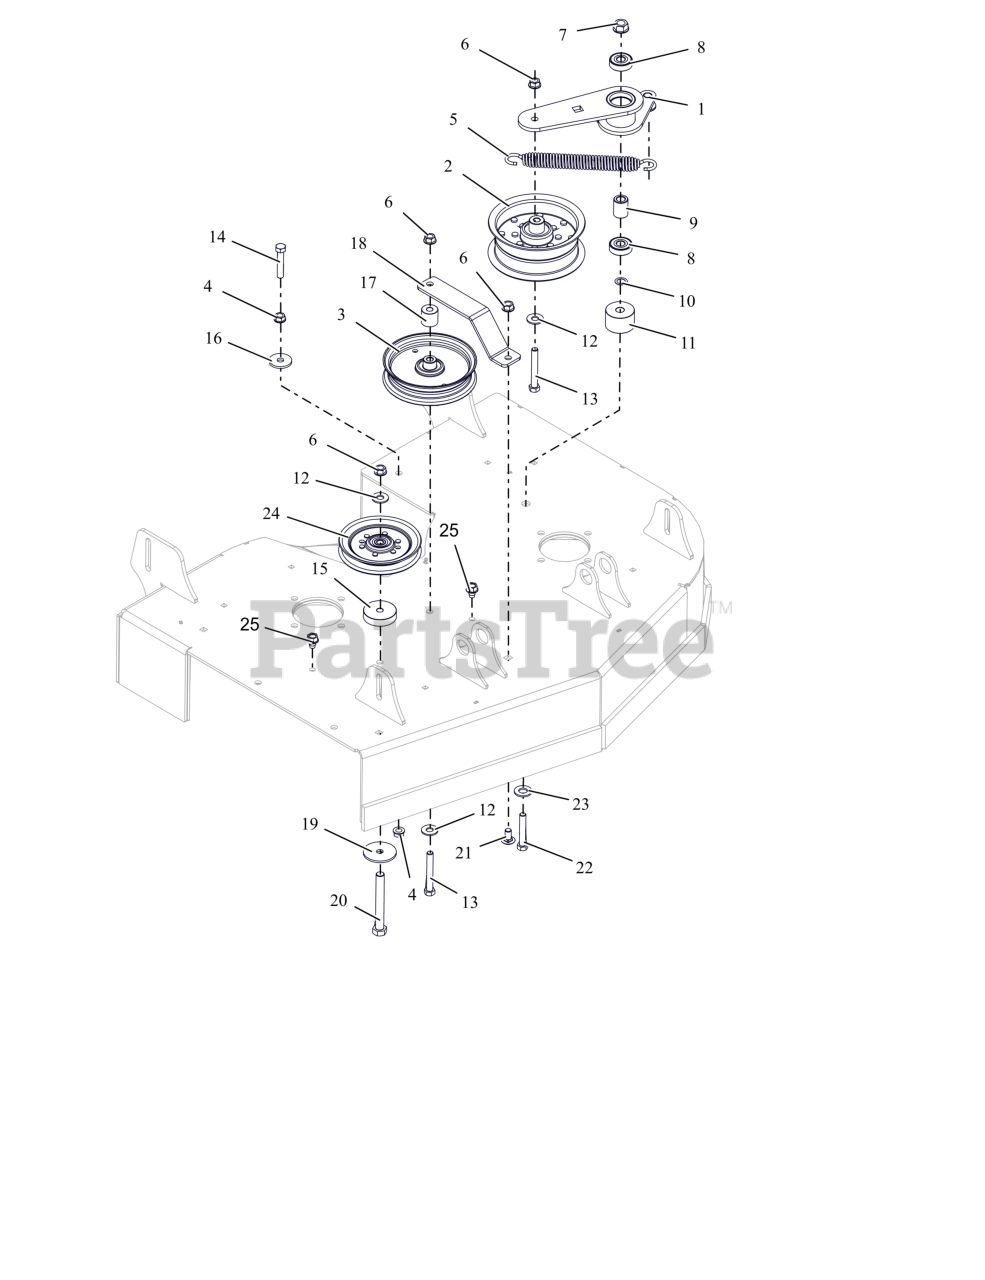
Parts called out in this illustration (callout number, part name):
1	WLDMT- IDLER ARM- 32" DECK
2	PULLEY, FLAT 5.00X2.36X.375
3	IDLER- FLAT - 5.00" X .75"
4	NUT, SPNLK-FLG .38-16 G5 ZCC
5	SPRING- EXTENSION
6	NUT-LK-CTR-FLG .375-16 GF ZCC
7	NUT-LK-CTR-FLG .500-13 GG ZCC
8	BRG-BALL .500X1.38X.437
9	SPACER .510 X .867 X 1.1485
10	WASHER, .500X.750X.020 THRUST
11	SPCR- DECK IDLER ARM
12	WSHR,FLT .438X1.00X.083 ZCC
13	BLT, HEX .38-16X2.75 G5 ZCC
14	BLT,HEX .38-16X2.00 G5 ZCC
15	SPCR, .380 X 2.000 X .500
16	WSHR,FLT .406X1.375X.135 ZCC
17	BUSHING- SLV .380 X .750 X .76
18	BRKT- 32" FIXED IDLER MTG(RED)
19	WSHR-FL-STL 0.406X2X0.125 ZCC
20	BLT, HEX .50-13X4.00 G5 ZCC
21	BLT, RHSSN .38-16X.75 G5 ZCC
22	BLT,HEX .38-16X2.25 G5 ZCC
23	WSHR,FLT .531X1.062X.095 ZCC
24	IDLER, V, 5.00X.38
25	SCR,TAP .375-16X.50 HWH TR ZCC
